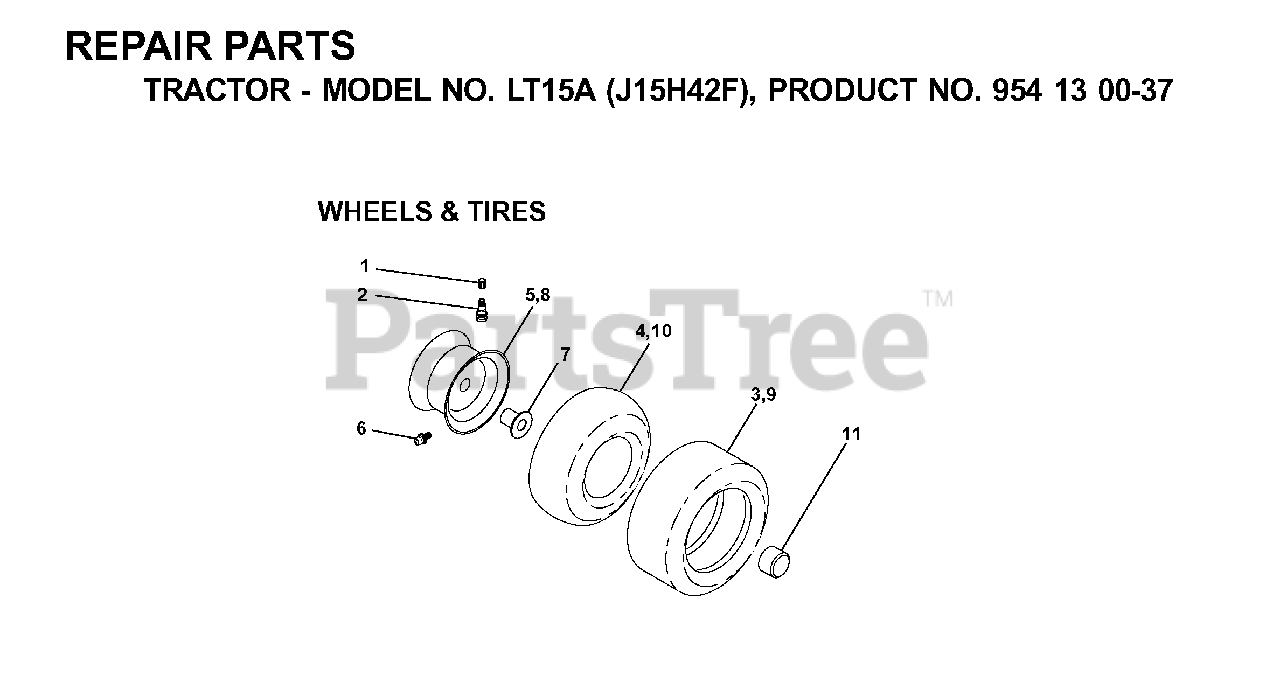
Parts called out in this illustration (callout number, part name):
1	VALVE CAP
2	VALVE STEM LT
3	TIRE HEAVY DUTY
4	TUBE.5.3/4.5/6
5	RIM ASM 6" FRONT SILVER
6	FITTING LT
7	BEARING T
8	RIM ASM 8" REAR SILVER
9	TIRE.TS.20X10-8
10	TUBE
11	CAP-HUB FRONT LT
